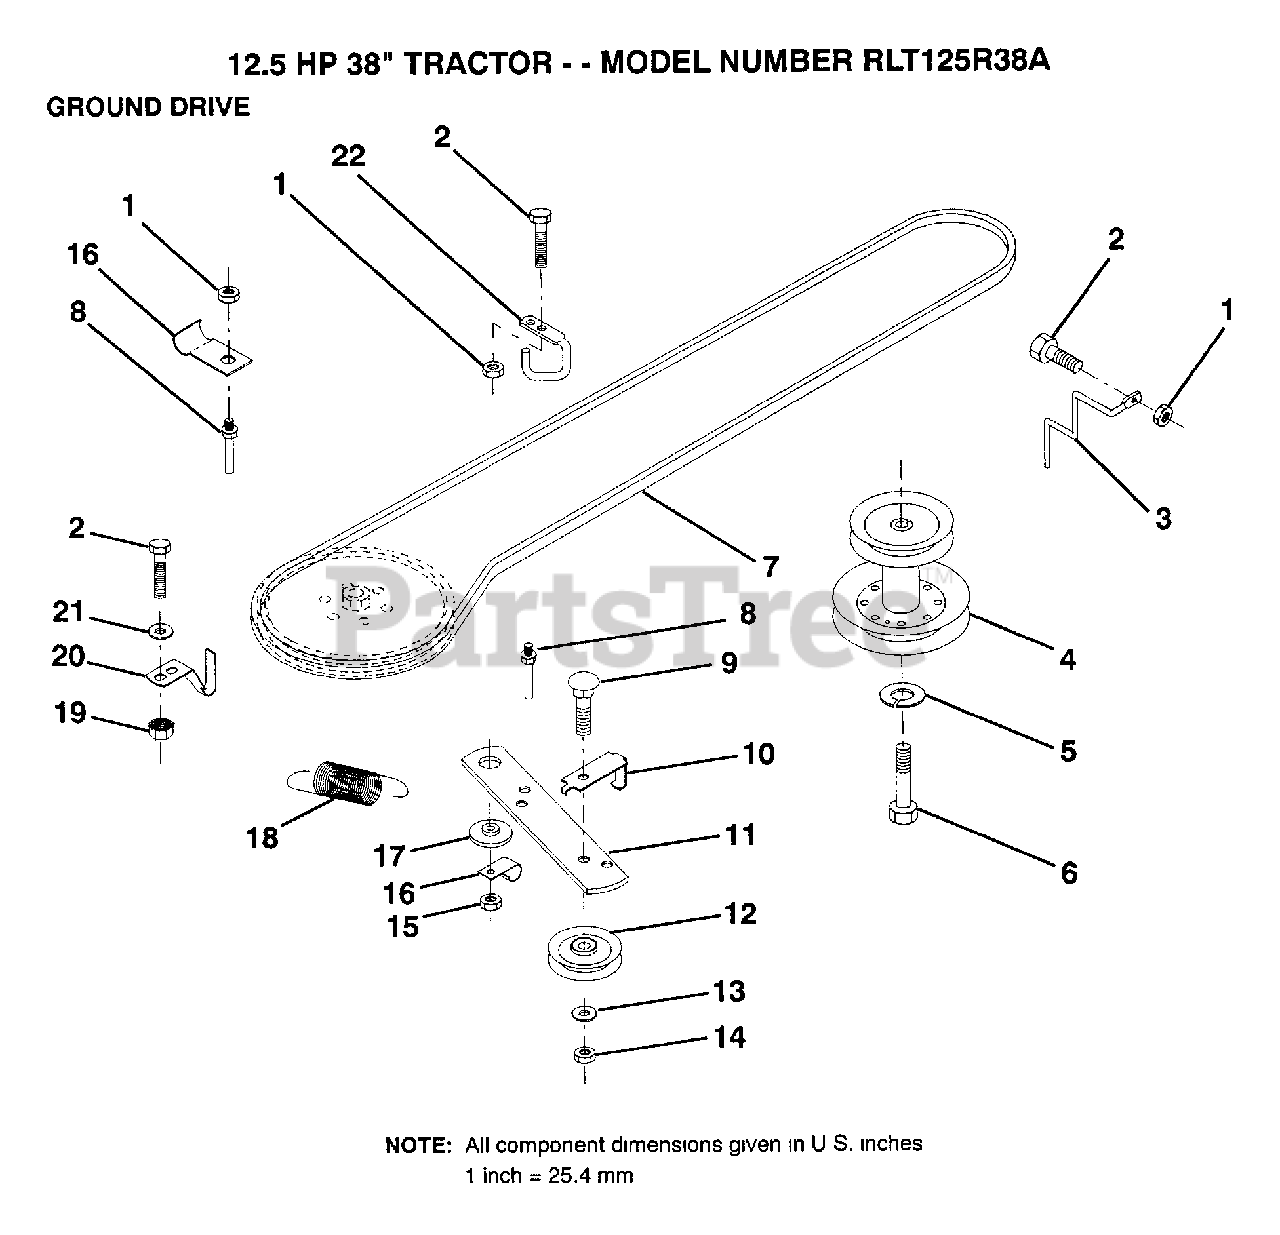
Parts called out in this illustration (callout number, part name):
2	BOLT
3	KEEPER MWR DR BLT
5	LOCKWASHER
6	BOLT
7	BELT
8	"KEEPER,DRIVE BELT"
9	BOLT
10	"KEEP,IDLER DR BEL"
13	WASHER
14	LOCKNUT
16	"CLIP,INSULATOR"
17	SPACER RETAINER
20	"KEEPER,DR BELT "
21	WASHER
22	"KEEPER,FRA DR BEL"
